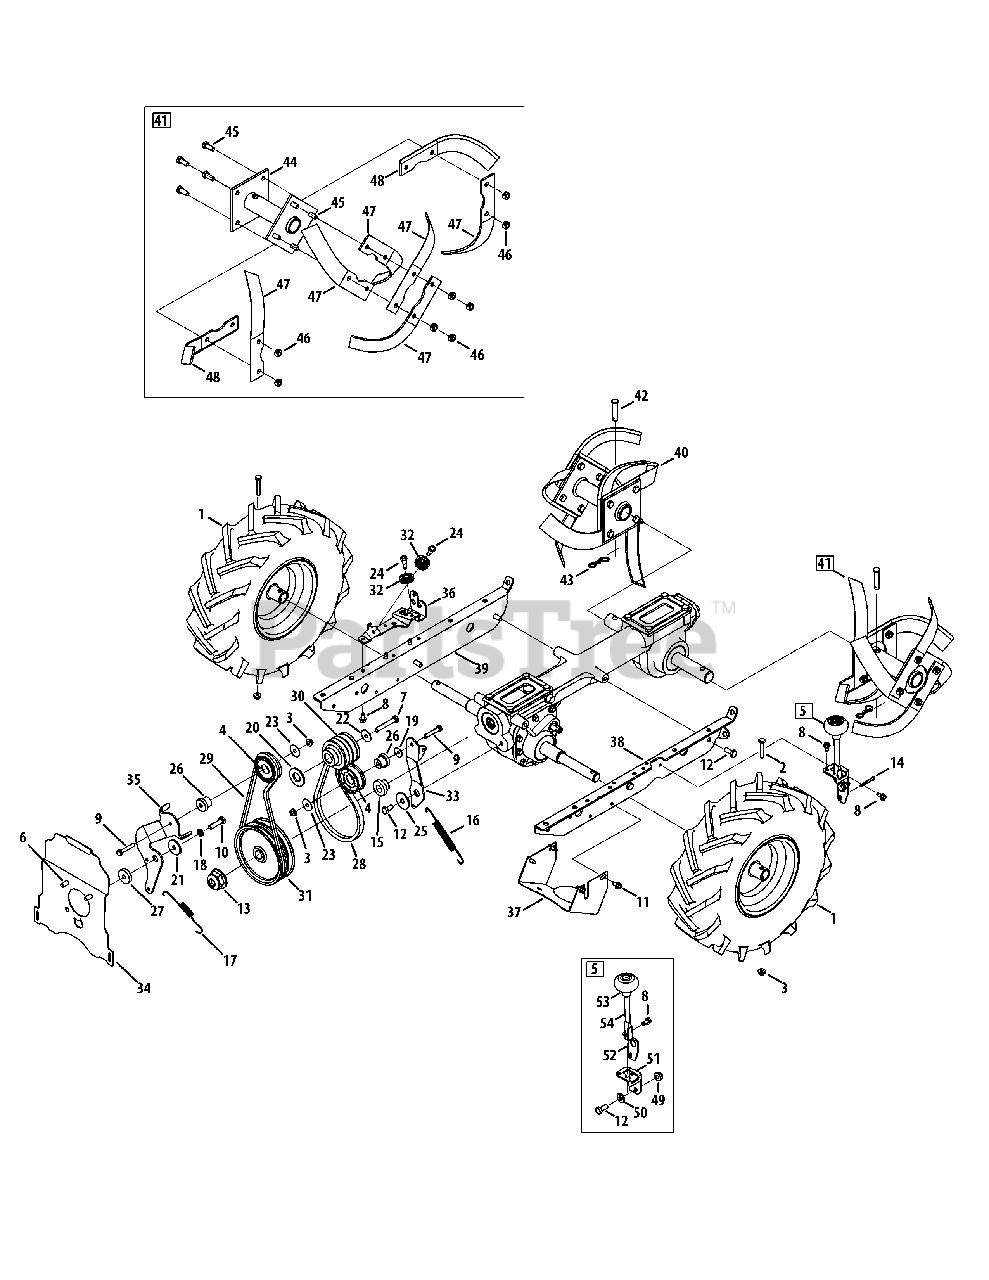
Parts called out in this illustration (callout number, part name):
1	Complete Whl. Ass., 14 x 4.5 x 6
1	Rim, 6.0 X 3.25
1	Tire, 14 x 4.5 x 6
2	Hex Head Screw, 1/4-20
3	Flange Lock Nut, 1/4-20
4	Idler Pulley Assembly
5	Pivot Bracket Assembly
6	Hex Head Screw, 5/16-24 x .625
7	Hex Head Screw, 3/8-24 x 2.25
8	Self-Tapping Screw, 1/4-20 x 1/2
9	Hex Head Screw, 1/4-20 x 1.50
10	Hex Head Screw, 5/16-18 x 1.25
11	Self Tapping Screw, 1/4-14 x .625
12	Hex Head Screw, 5/16-18 x .75, Patch
13	Nut, 9/16-18, Flange Lock
14	Cotter Pin, 5/32 x 1.25
15	Hub, 5/8 Spline
16	Extension Spring, .480 OD X 5.00 LG
17	Extension Spring, LT5 PTO
18	Lock Washer, 5/16
19	Washer, .28 x .74 x .063
20	Washer, Flat, .760 x 1.50 x .120
21	Flat Washer, .330 X 1.25 X .120
22	Bell Washer, .396 x 1.140 x .095
23	Flat Washer, .265 x 1.0 x .030
24	Shoulder Screw, .342 x .335 1/4-28
25	Pivot Idler Spacer
26	Shoulder Spacer, .260 x .785 x .538
27	Pivot Idler Spacer
28	V-Belt, 4L x 25.375 Long
29	V-Belt, 3L x 29.125 Long
30	Engine Pulley
31	Transmission Pulley
32	Cable Roller
33	Idler Bracket, Forward
35	Idler Bracket, Reverse
36	Pulley Bracket
37	Pulley Shield
38	Mounting Frame, LH
39	Mounting Frame, RH
40	Tine Assembly, RH
41	Tine Assembly, LH
42	Clevis Pin, .375 x 1.75
43	Cotter Pin, Bow Tie
44	Tine Holder Assembly
45	Hex Head Screw, 5/16-18 x .75
46	Nut, 5/16-18, Hexlock
49	Nylon Hex Lock Nut, 5/16-18
50	Pivot Spacer
51	Pivot Wheel Mounting Bracket
52	Pivot Wheel Bracket
